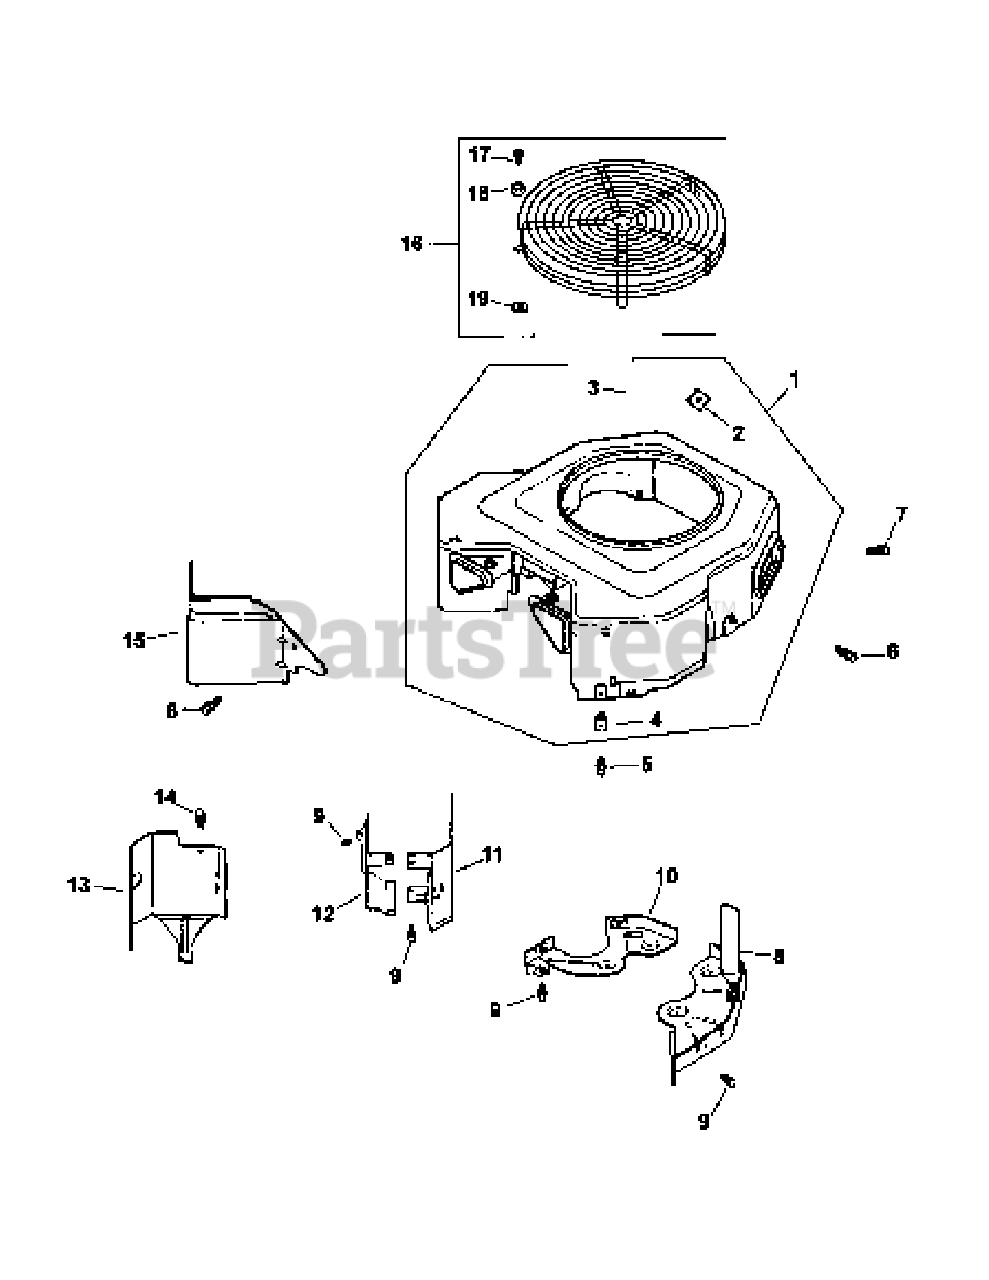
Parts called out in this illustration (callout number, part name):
1	Housing, Blower
5	Screw, Hex Flange M5x0.8x20
6	Screw, Hex Flange M5x0.8x16
7	Screw, Hex Flange M5x0.8x16
8	Plate, Backing #2 Side
9	Screw, Hex Flange M6x1.0x16
10	Plate, Backing #1 Side
11	Baffle, Cylinder Barrel #2
12	Baffle, Valley #1 Side
13	Baffle, Cylinder Barrel #1 Side
14	Screw, Hex Flange M5x0.8x10
15	Baffle, Valley #2 Side
17	Screw Pan hd. M5x0.8x15
18	Spacer
19	Washer, Plain 1/4"
